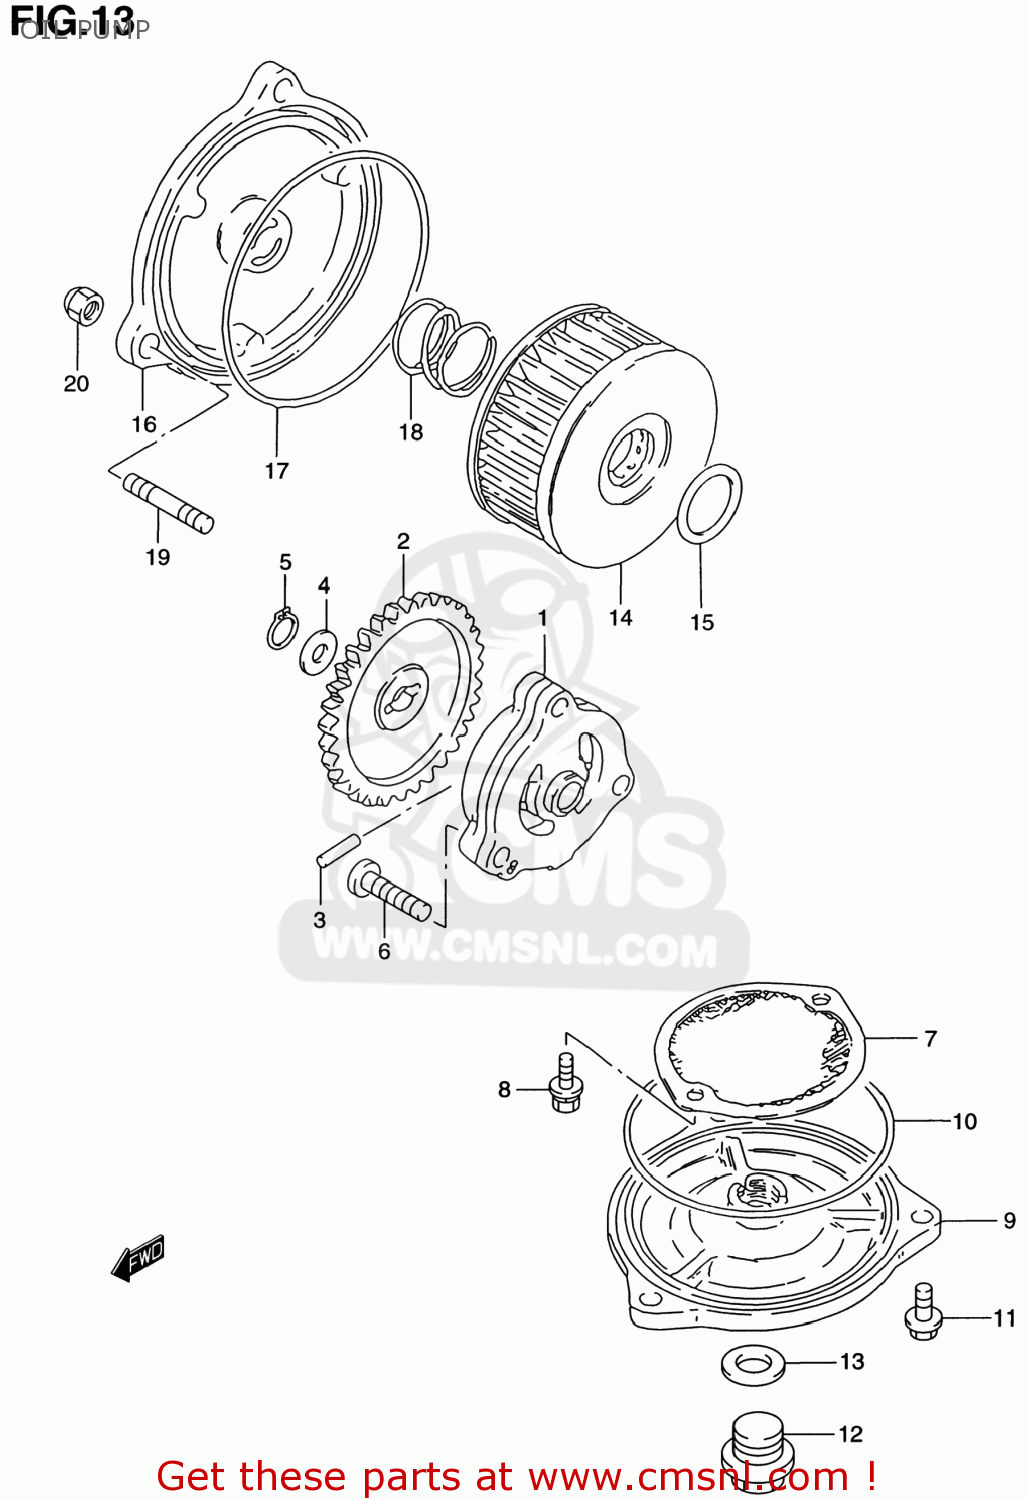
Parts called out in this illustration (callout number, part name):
1	PUMP ASSY,ENGINE OIL
2	GEAR,OIL PUMP DRIVEN(NT:33)
3	PIN(4X15.8)
4	SHIM(10X18X0.5)
5	CIRCLIP,10MM
6	SCREW
7	STRAINER,ENGINE OIL
8	SCREW
9	CAP,OIL STRAINER
10	O RING(D:2.4,ID:85)
11	SCREW
12	PLUG(14X12)
13	GASKET(13.8X18.8X4.8) (NAS)
14	FILTER ASSY,ENGINE OIL
15	O RING(D:2.4,ID:15.8)
16	CAP,OIL FILTER
17	O RING(D:2.4,ID:73)
18	SPRING
19	STUD 6X12
20	NUT
